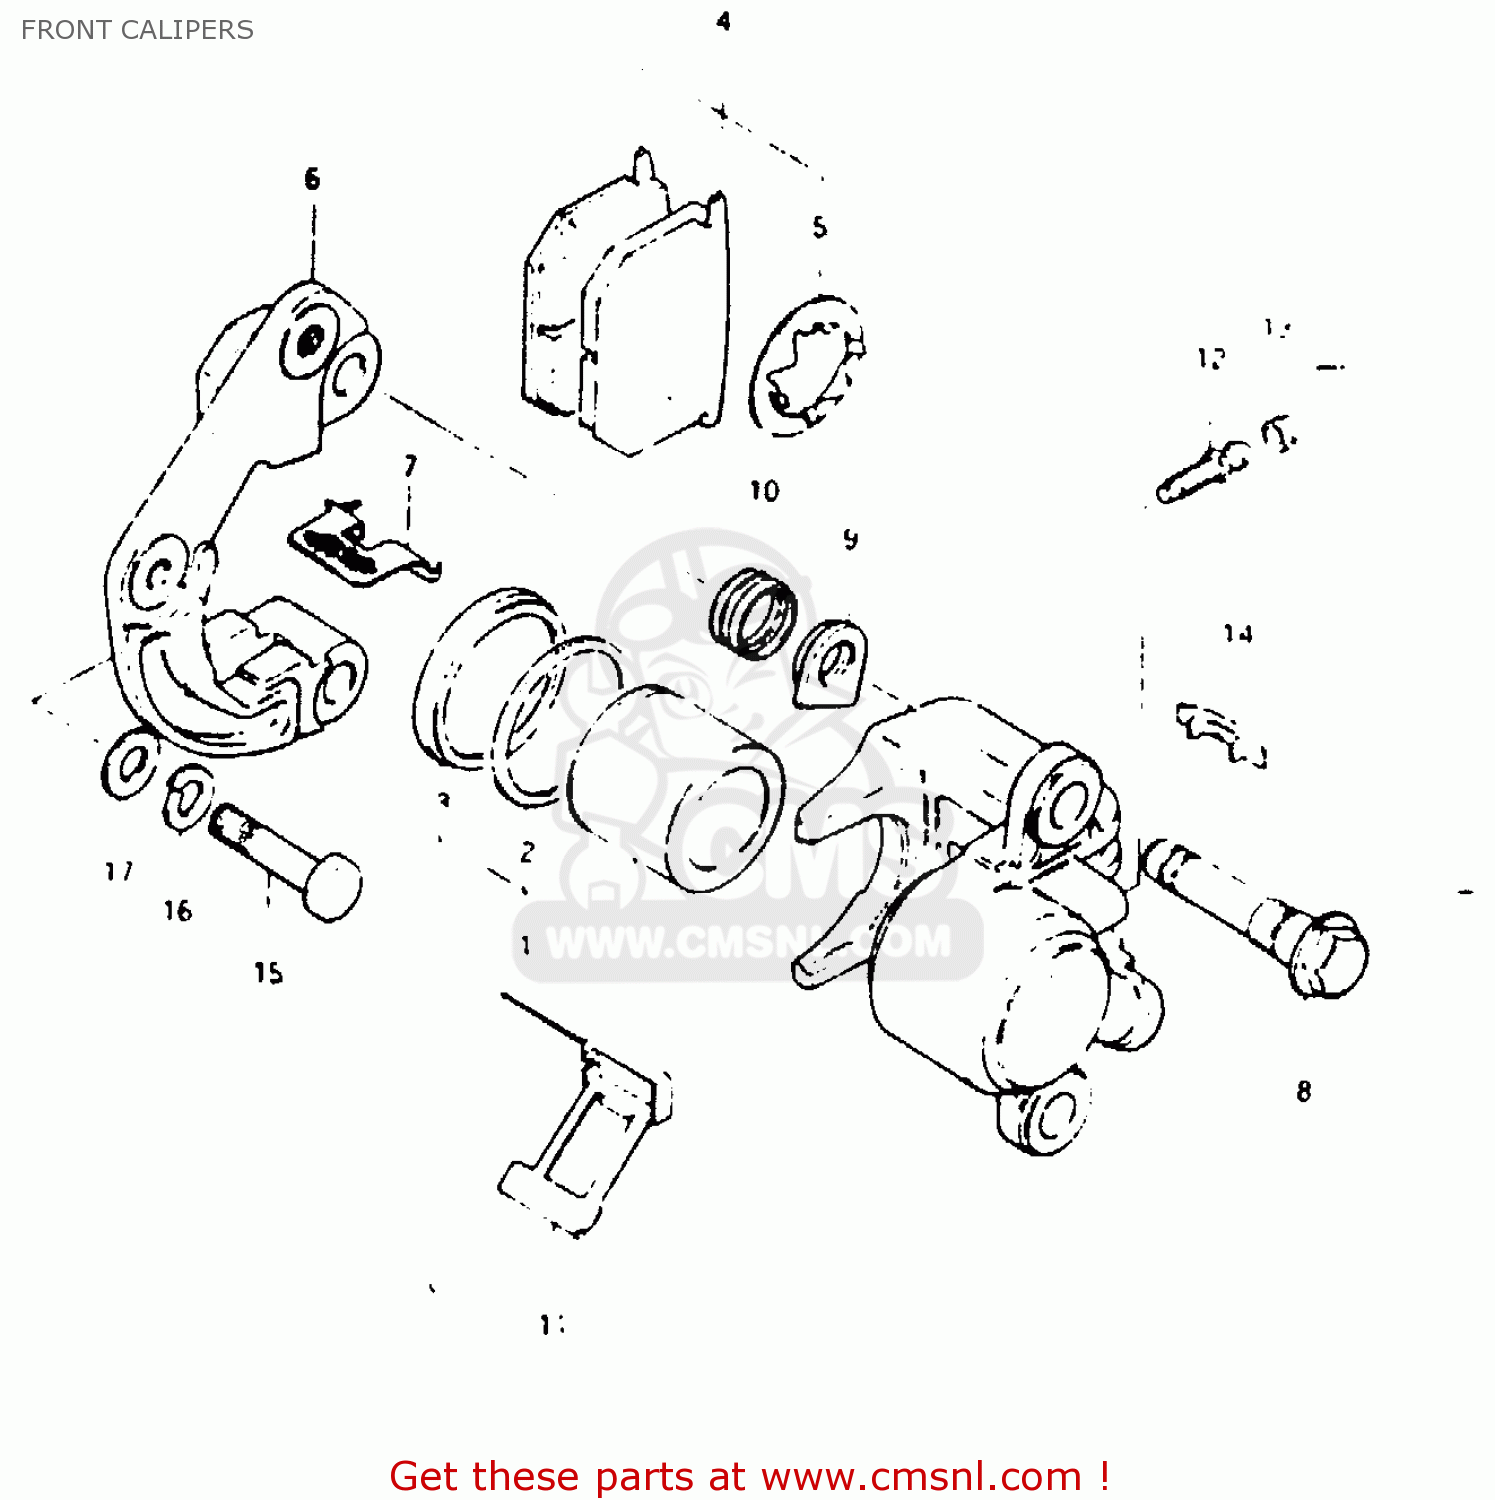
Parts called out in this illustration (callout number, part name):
1	PISTON SET
2	SEAL,PISTON
3	BOOT,PISTON
4	PAD & SHIM SET (MCA)
5	SHIM,PAD
6	HOLDER,CALIPER,LEFT
7	PAD,GUIDE
8	AXLE,CALIPER
9	NUT,CALIPER AXLE
10	BOOT
11	SPRING
12	BREATHER
13	CAP,BLEEDER PL
14	COVER,INDICATOR
15	BOLT
16	LOCK WASHER
17	WASHER
